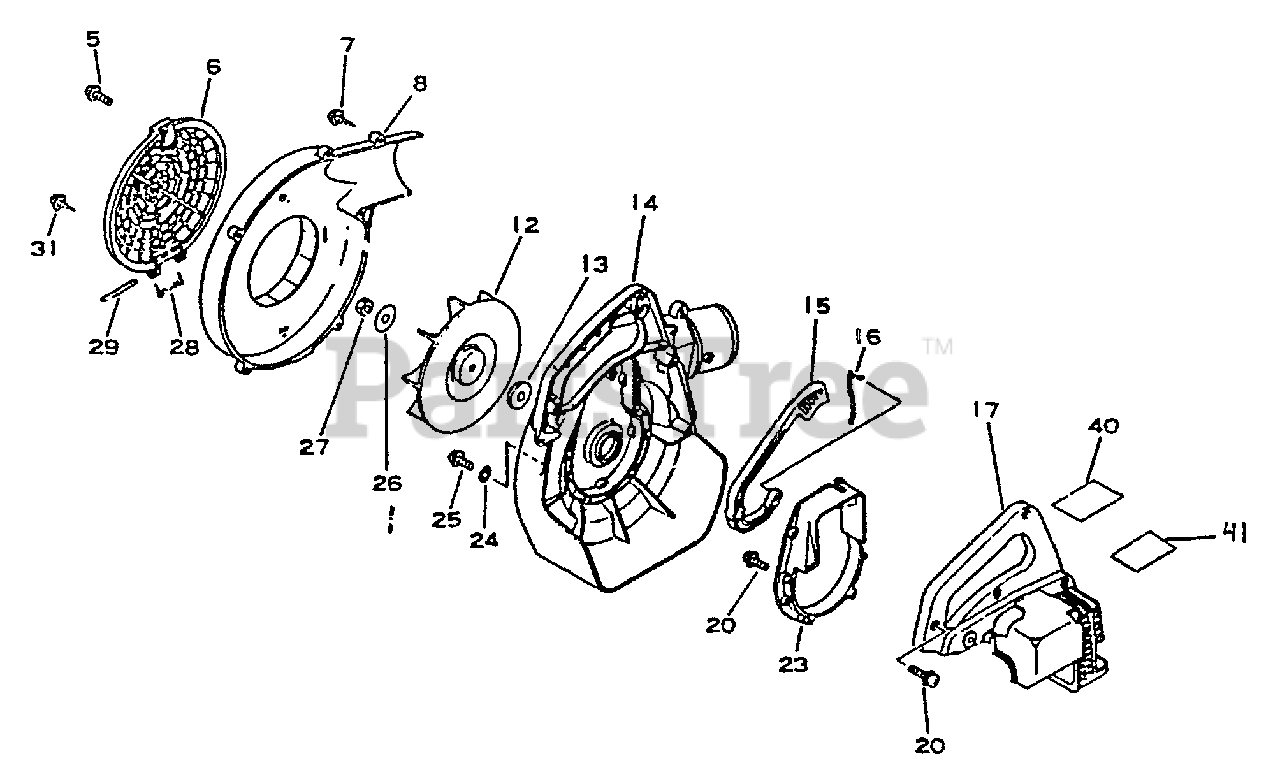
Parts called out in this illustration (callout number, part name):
5	SCREW - 5X18
6	GUARD, DEBRIS
7	SCREW - 5X20
8	COVER, FAN - LEFT
12	FAN
13	WASHER - 8
14	COVER, FAN - RIGHT
15	TRIGGER, THROTTLE
16	ROD, THROTTLE
17	COVER, ENGINE
20	SCREW - 4X18
23	BRACKET, ENGINE
25	SCREW - 4X22
26	WASHER - 8
31	SCREW - 5X20
40	LABEL - MODEL
41	LABEL - CAUTION
